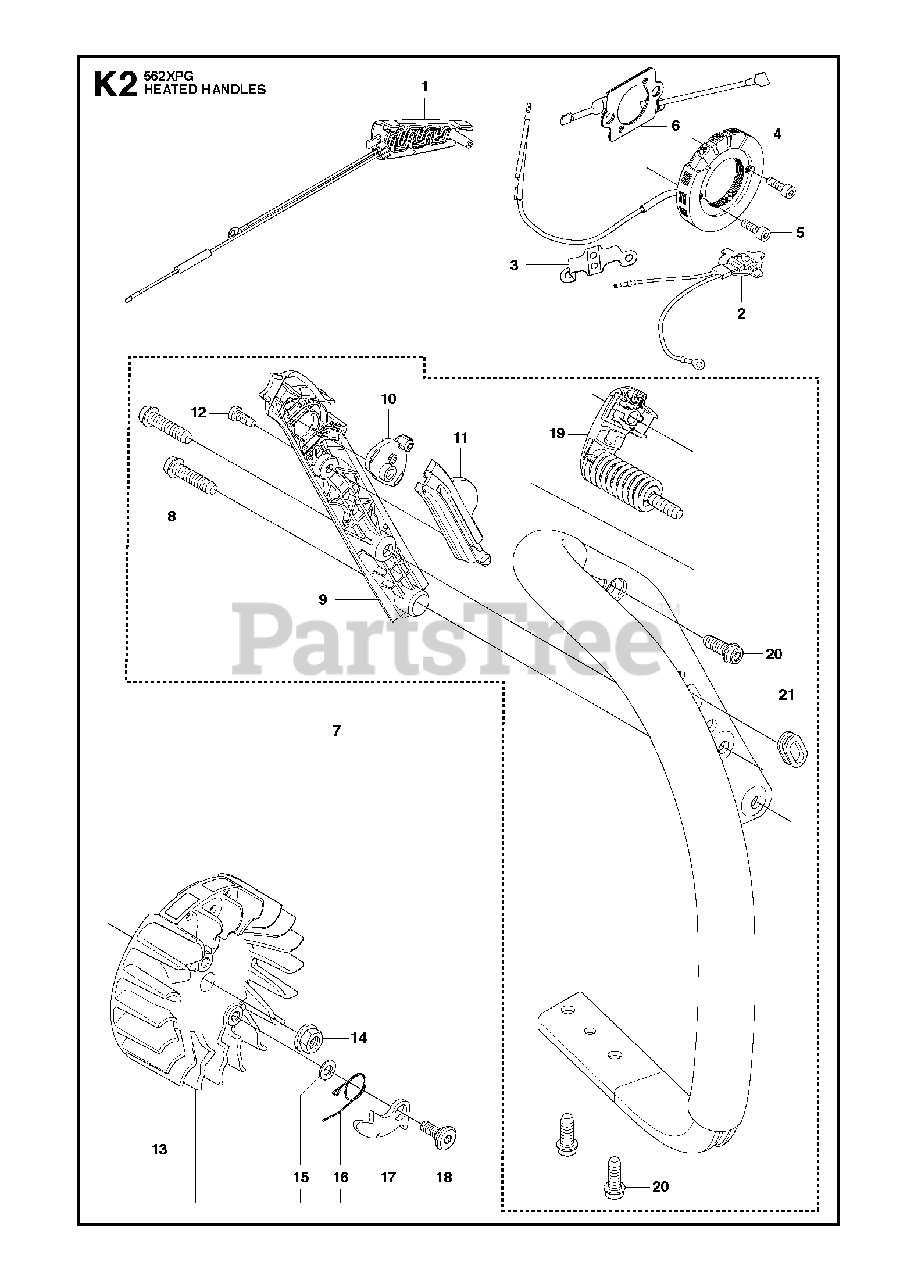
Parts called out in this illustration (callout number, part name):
1	HANDLE INSERT
2	THERMOSTAT ASSY
4	GENERATOR STATOR
6	FOIL ELEMENT
7	FRONT HANDLE
8	SCREW
9	COVER
10	HANDLE
11	CONTACT PLATE
12	SCREW
13	FLYWHEEL ASSY
14	NUT W/ WASHER
15	WASHER
16	SPRING
17	PAWL
18	SCREW M5X14
19	ANTIVIBRATION ELEMENT
20	SCREW IHSCFT
21	GROMMET
